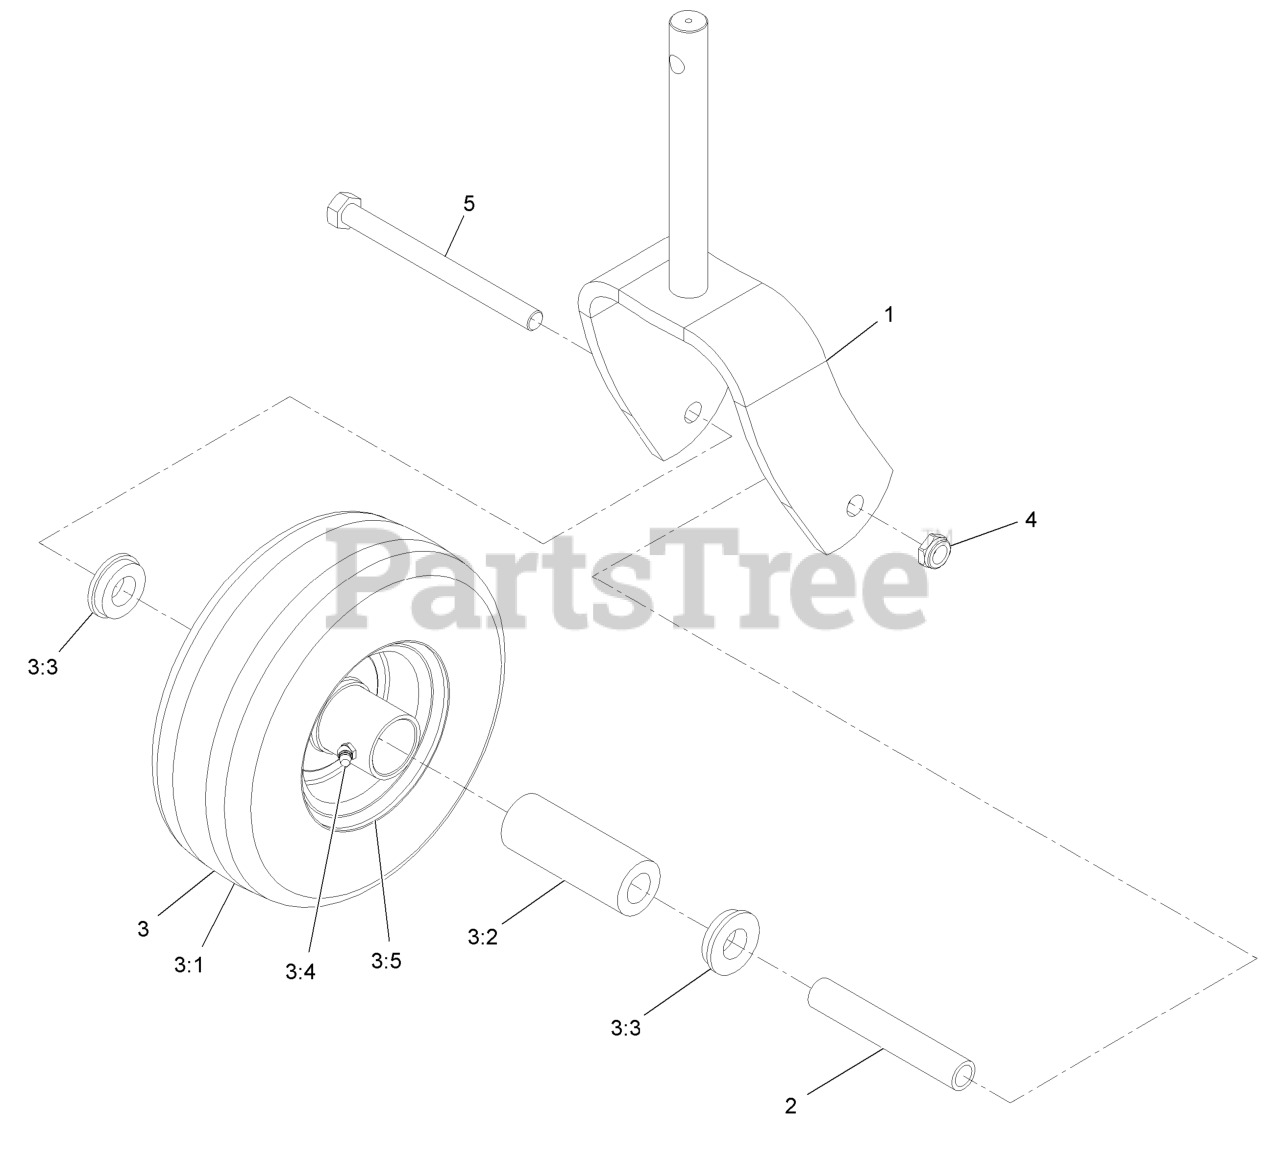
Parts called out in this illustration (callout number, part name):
1	FORK-CASTER
3	Wheel And Tire ASM
3:1	Tire
3:2	BEARING
3:3	BUSHING
3:4	FITTING-GREASE
3:5	Wheel
4	NUT-HEX
5	SCREW-HH
